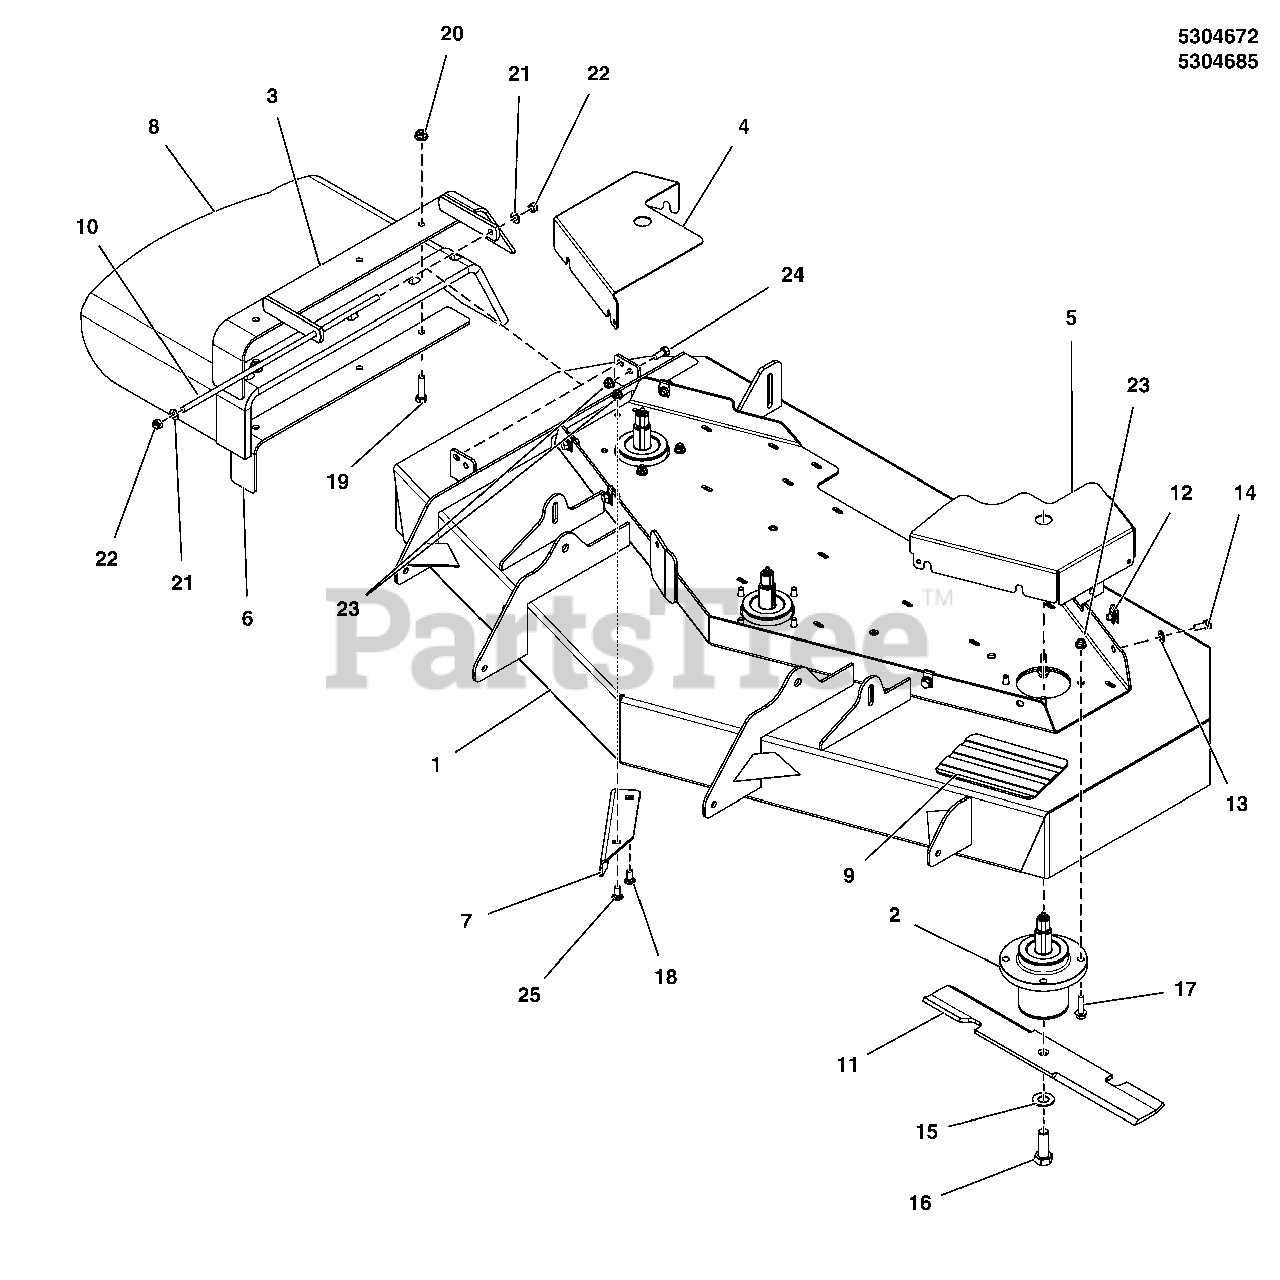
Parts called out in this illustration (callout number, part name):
1	DECK SHELL W/DECALS, 52, 560 (5415615D)
2	SPINDLE ASSEMBLY, Complete (See Spindle Service Parts group)
3	WELD, MOUNT, DISCHARGE CHUTE - BLK
4	GUARD, 52", RH, 560Z - RED
5	GUARD, 52 DECK, LH - RED
6	SUPPORT, DISCHARGE CHUTE - BLK
7	PLATE, Deflector
8	CHUTE, RUBBER DISCHARGE (5104442)
9	SAFETY WALK, 4.00 X 7.50
10	MOUNT, Chute
11	BLADE, 18", .63 Hole, .98 Lift
12	CLIP, BODY , 5/16-18 FOR 7 GA.
13	WASHER, Flat, 5/16
14	CAPSCREW, Hex Head, 5/16-18 x 3/4
15	WASHER, Blade Bolt, 9/16"
16	BOLT, 5/8-11 X 1 3/4, GR 8
17	CAPSCREW, Hex Flange Head, 5/16-18 x 1-1/4
18	BOLT, 5/16-18 X 3/4, CARRIAGE, GD5, CZ
19	BOLT, Carriage, 3/8-16 X 1 1/2, GR5
20	NUT, Hex Flange, Nylock, 3/8-16
21	WASHER, Flat, 5/16
22	NUT, Hex Lock, Nylon, 5/16-24
23	NUT, Flange Nylock, 5/16-18
24	CAPSCREW, Hex Head, 5/16-18 x 3/4
25	BOLT, 5/16-18 X 1, CARRIAGE YZ
